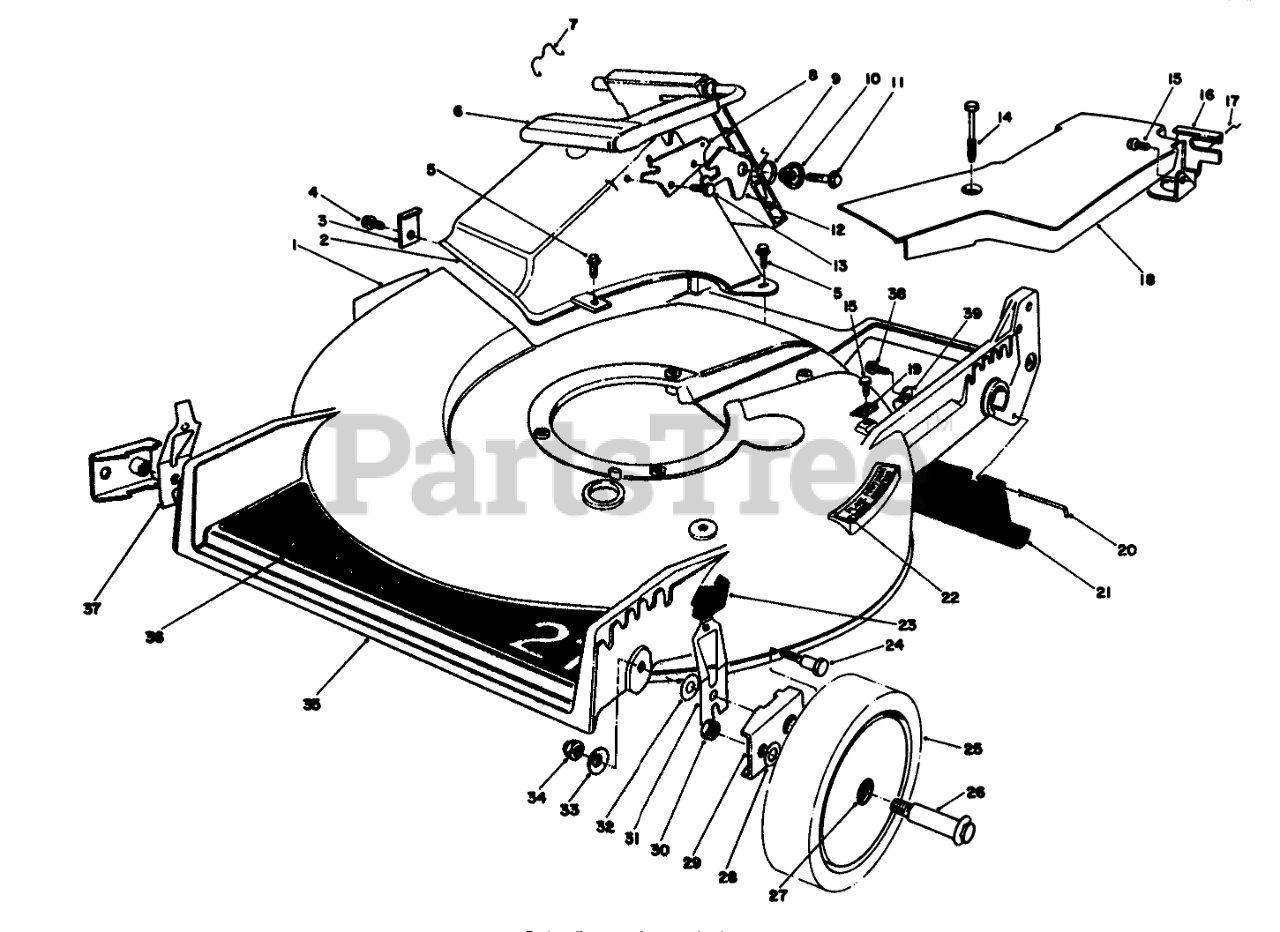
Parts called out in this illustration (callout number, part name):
1	Decal-Danger
2	Tunnel Discharge
3	TUNNEL CLIP
4	SCREW
5	SCREW-HWH
6	Discharge Door Assembly
7	DOOR RET SPRING
8	DOOR LATCH PLATE
9	TORSION SPRING
10	DOOR SPACER
11	SCREW-HWH
12	SAFETY LATCH
13	SCREW-PLASTITE
14	SCREW-HHFTF
15	SCREW-HWHTF
16	Bracket-Traction Adj.
17	RETAINER-CABLE
18	Belt Cover
19	CLAMP-CABLE
20	ROD-SHIELD
21	Shield-Trailing
22	STEP PAD DECAL
23	KNOB-ARM
24	PIVOT SCREW
25	Wheel & Tire Assembly (Incl. Ref. #27)
26	BOLT-WHEEL
27	BUSHING
28	WASHER
29	HP PIVOT ARM ASM
30	Nut
31	L. HP SPRING ARM ASM
32	WASHER-PIVOT
33	WASHER-BELLEVILLE
34	NUT-LOCK, NI
35	Housing (Incl. Ref. #1, 5 & 22)
36	DECK DECAL
37	R HP SPRING ARM ASM
38	SCREW
39	CLAMP-CABLE
